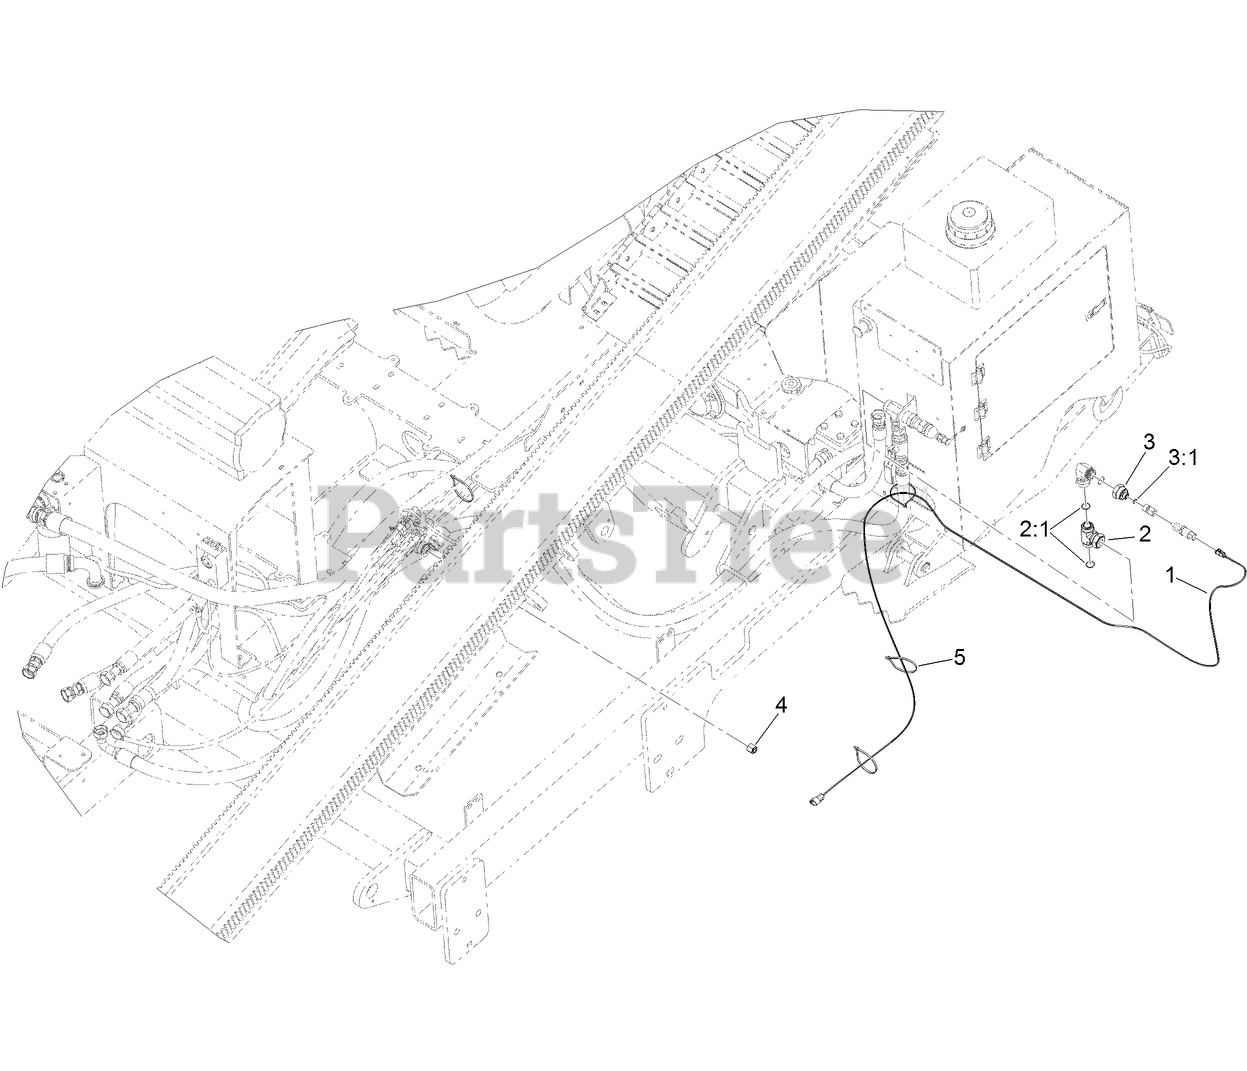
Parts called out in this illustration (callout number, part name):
1	HARNESS-WIRE
2	FITTING-TEE
2:1	O-RING
3	FITTING-REDUCER
3:1	O-RING
4	CAP-HYD
5	TIE-CABLE
